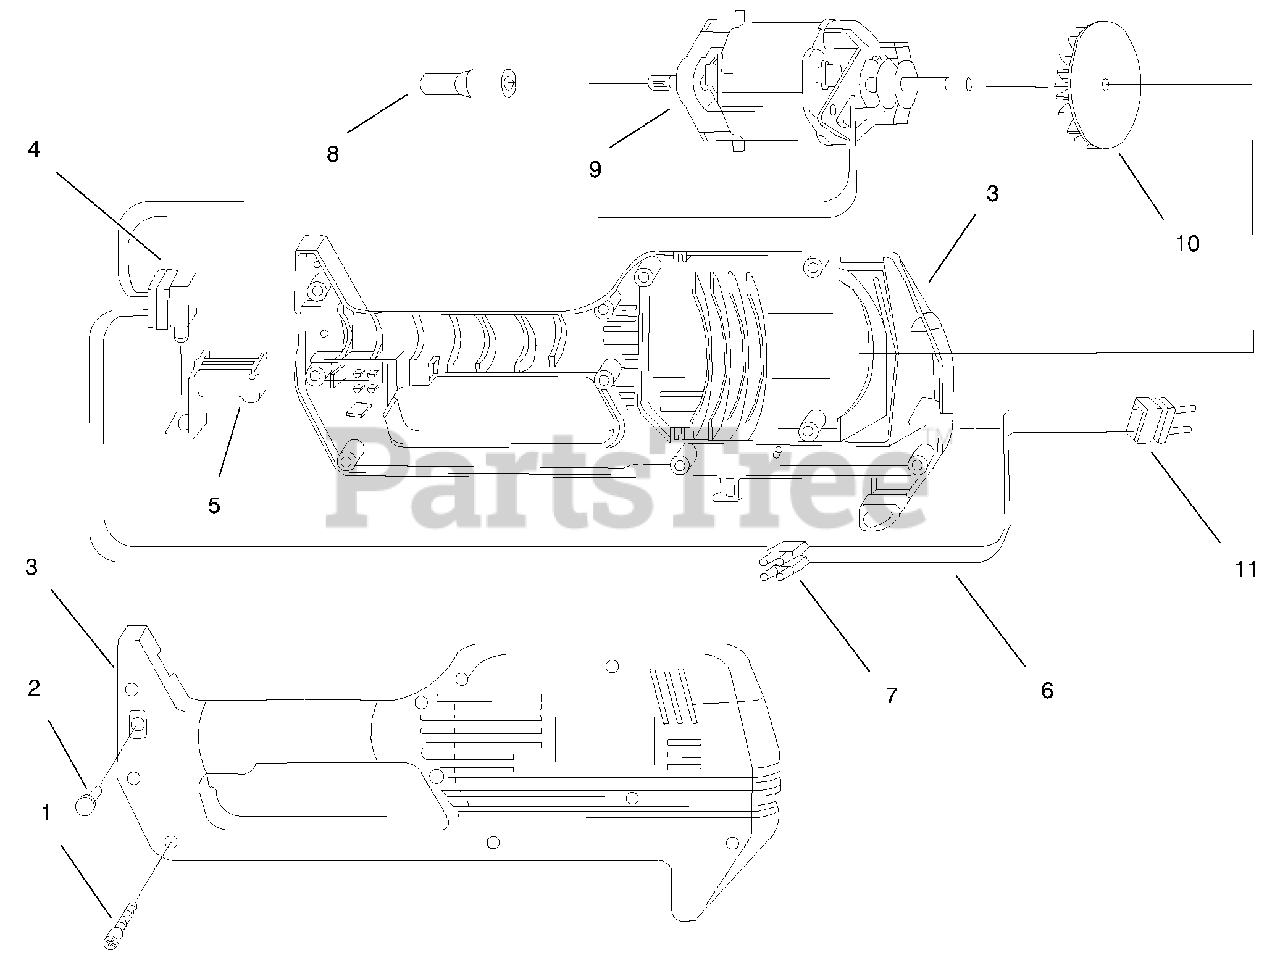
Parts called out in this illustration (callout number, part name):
2	Anti-Rotation Screw
3	Motor Housing
4	Switch Assembly
5	Trigger
6	Wire Lead
7	Terminal Block
9	Motor (Incl. Ref. #8-10)
10	Cooling Fan
11	Harness
